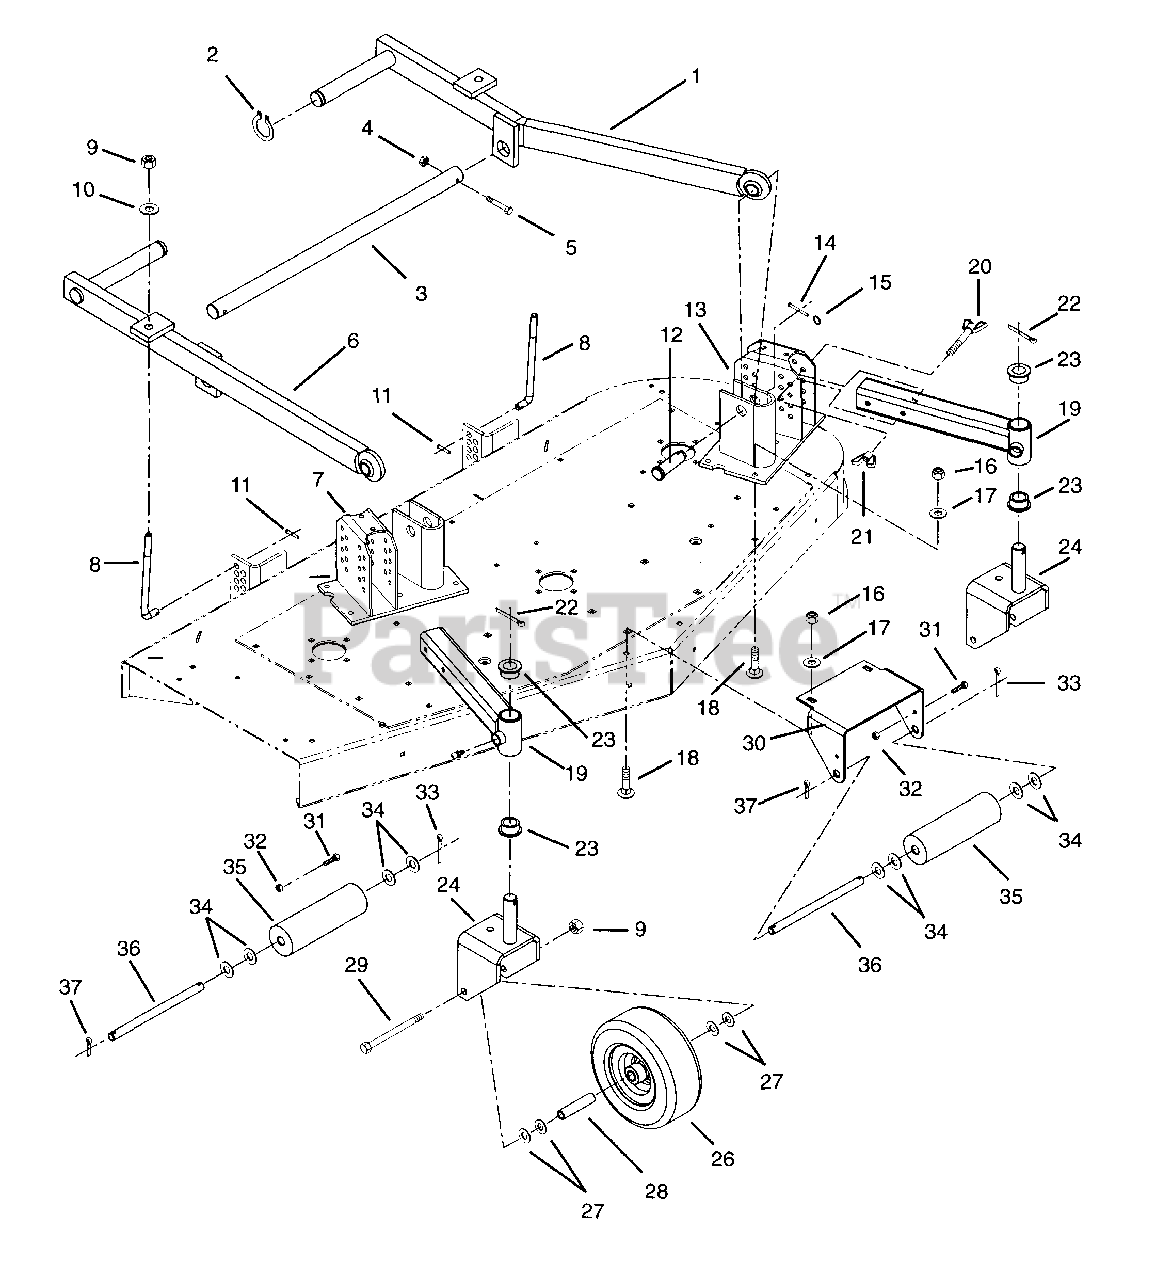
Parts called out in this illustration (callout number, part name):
1	Weldment, Lift Arm Left Hand
2	Ring-Retaining-External 1.150 x .093
3	Shaft, Mower Lift
4	Nut-Locking-Jam-Center .375-16
5	Bolt-Hex .25-20 x 1.75 Grade 2
6	Weldment, Lift Arm Right Hand
7	Weldment, Lift Arm Mount Right Hand
8	Rod, Rear Height Adjustment
9	Nut-Locking-Nylon .50-13 Grade 5
10	Washer-Flat-Steel .531 x 1.250 x 1.00
11	Pin-Klik 1.000 x .188 x 1.25
12	Pin-Clevis .875 x 3.00
13	Weldment, Lift Arm Mount Left Hand
14	Pin-Clevis .313 x 2.62 Grade 5
15	Ring-Retaining-External 2.240 x .180
16	Nut-Locking-Nylon .375-16 Grade 2
17	Washer-Flat-Steel .406 x .812 x .065
18	Bolt-Round Head Square Neck .38-16 x 1.0
19	Caster Wheel Mount
20	Bolt, Wing 3/8-16 x 3
21	Nut, Wing 3/8-16
22	Pin-Cotter .188 x 1.625
23	Bushing-Flange 1.020 x 1.385 x .75 x 1.75
24	Weldment, Caster Fork
25	Fitting-Lube .25-28 x .256
26	Wheel 9 x 3.50
27	Washer-Flat-Steel .500 x 1.250 x .083
28	Spacer .532 x .748 x 3.34
29	Bolt-Hex .50-13 x 5.50
30	Bracket, Roller Right Hand
31	Bolt-Hex .25-20 x .75 Grade 5
32	Nut-Locking-Nylon .250-20 Grade 2
33	Pin-Cotter .250 x 2.00
34	Washer-Flat-Steel .656 x 1.312 x .095
35	Roller, Gage
36	Shaft, Center Roller
37	Pin-Cotter .25 x 1.00
